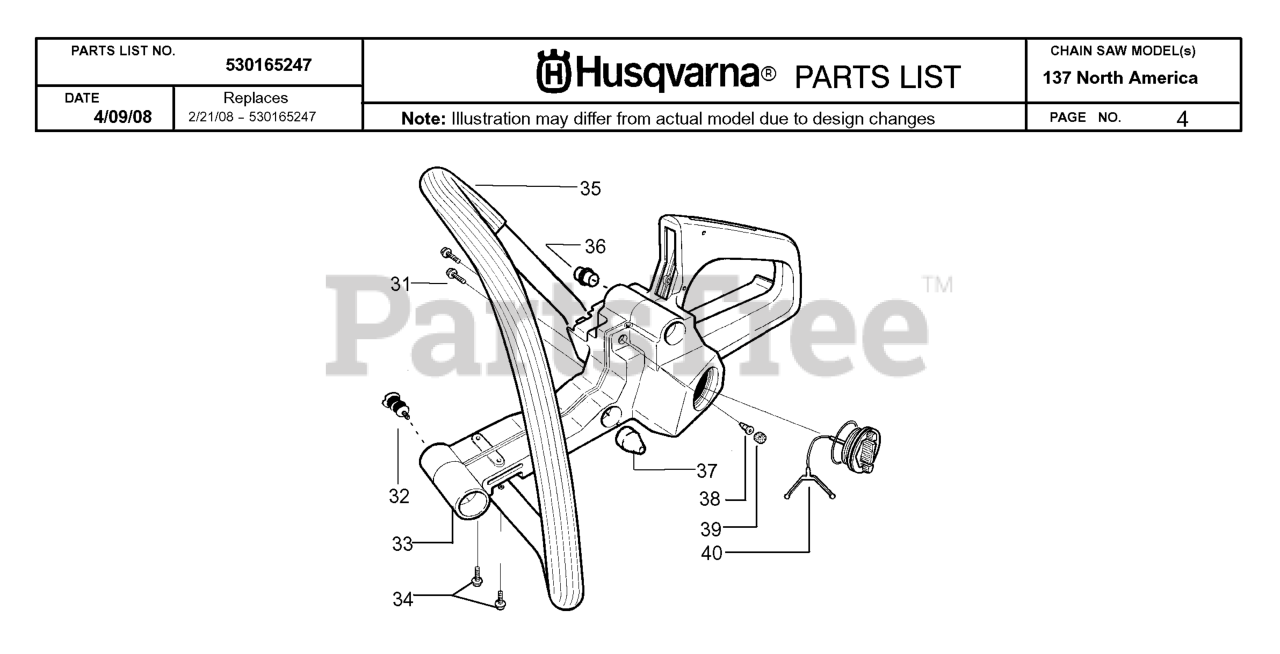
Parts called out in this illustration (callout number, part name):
33	TANK HANDLE ASSY
35	HANDLE FRONT
36	FRONT HANDLE ISOLATOR
37	SHOCK MOUNT(X2) 36/41
38	VALVE-CHECK (DUCKBILL)
39	BRONZE PLUG
40	FUEL CAP KIT
